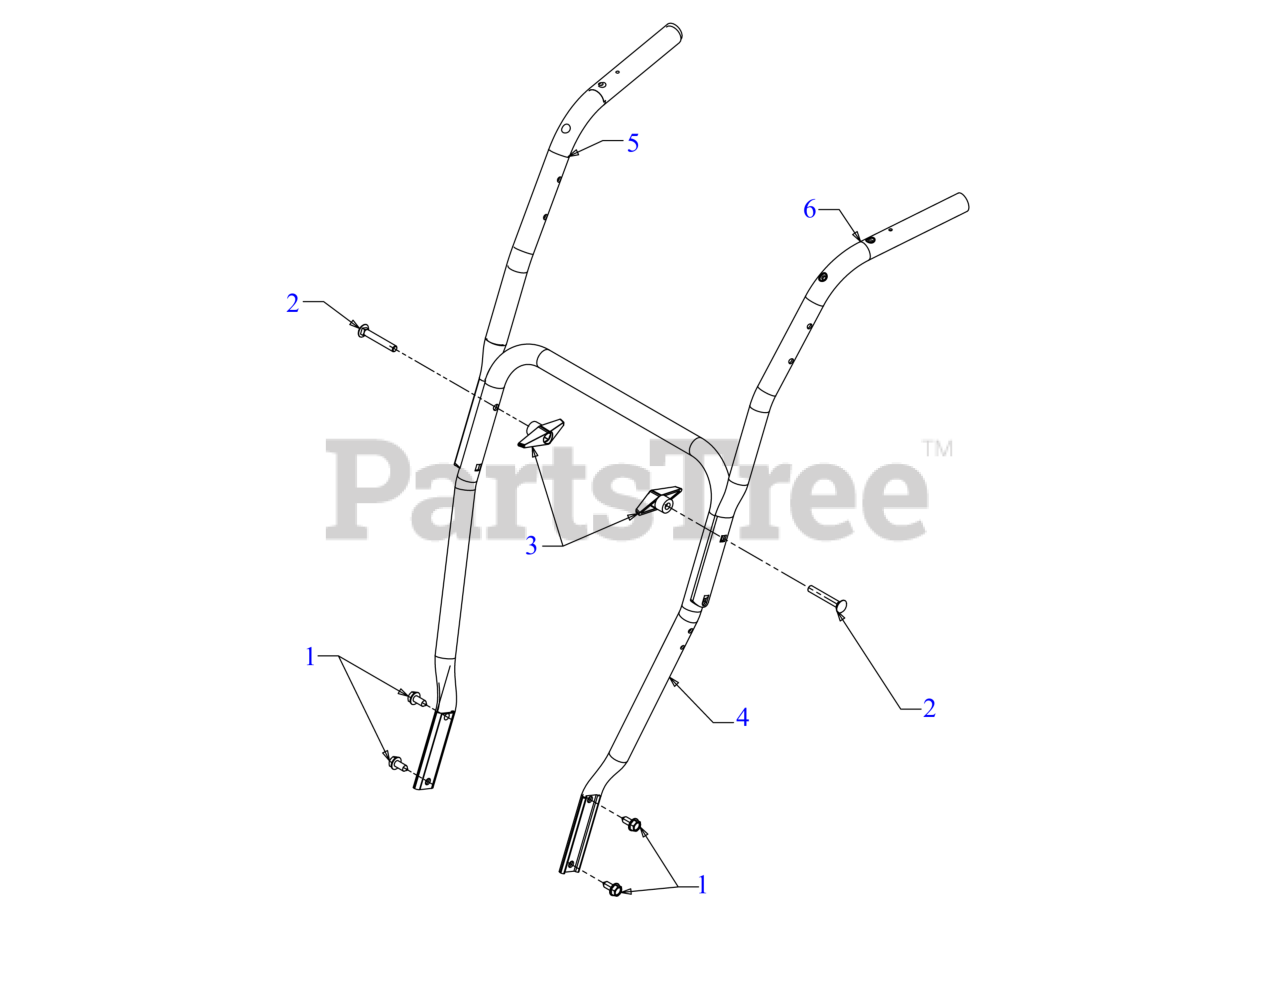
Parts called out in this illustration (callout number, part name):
1	SCREW 5/16-18 x .750
2	BOLT 5/16-18 x 2.50 GR1
3	WING KNOB NUT
